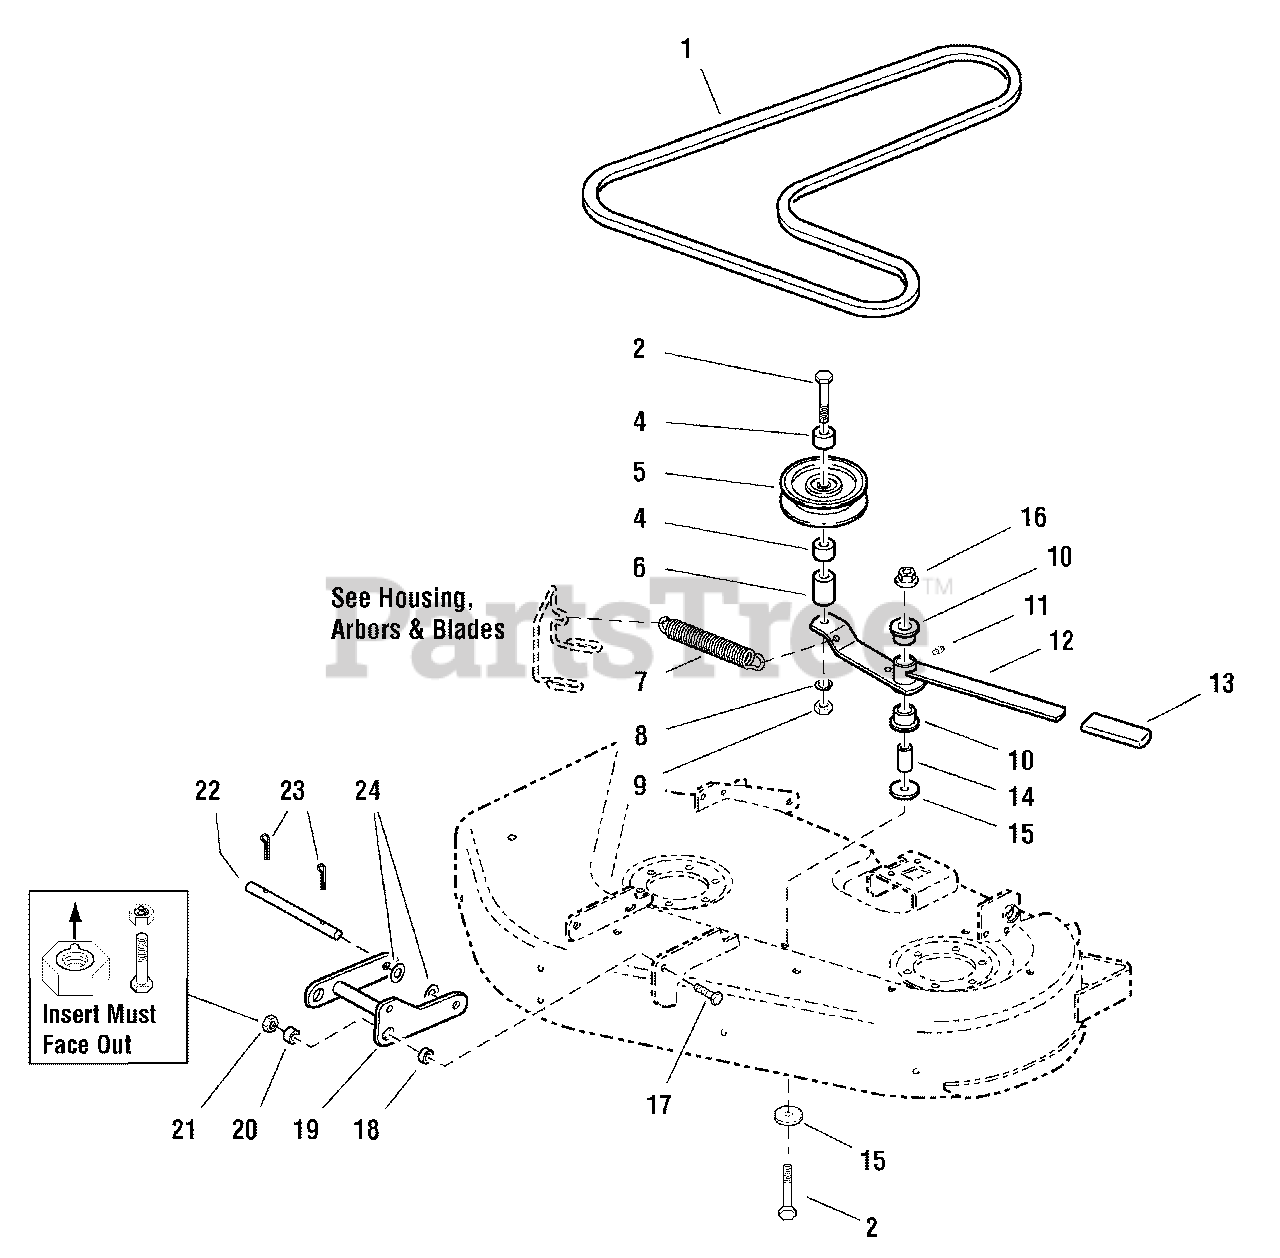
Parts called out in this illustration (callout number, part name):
1	BELT, V-Belt 34" Mower Power Take Off
2	CAPSCREW, Hex Head, 3/8-16 x 2-3/4, Black
5	PULLEY, Idler
7	SPRING, Extension
8	LOCKWASHER, 3/8
9	NUT, Hex, 3/8-16
11	FITTING, Lube
12	LEVER & ARM ASSEMBLY, Complete (Includes Ref. No. 10 & 11)
13	GRIP
15	WASHER, 3/8
16	NUT, Hex Serrated Flange, 3/8-16
17	CAPSCREW, Hex Head, 3/8-16 x 1-1/2
18	SPACER
21	NUT, Hex Lock, Aluminum Insert, 3/8-16
23	PIN, Cotter
24	WASHER, 1/2
